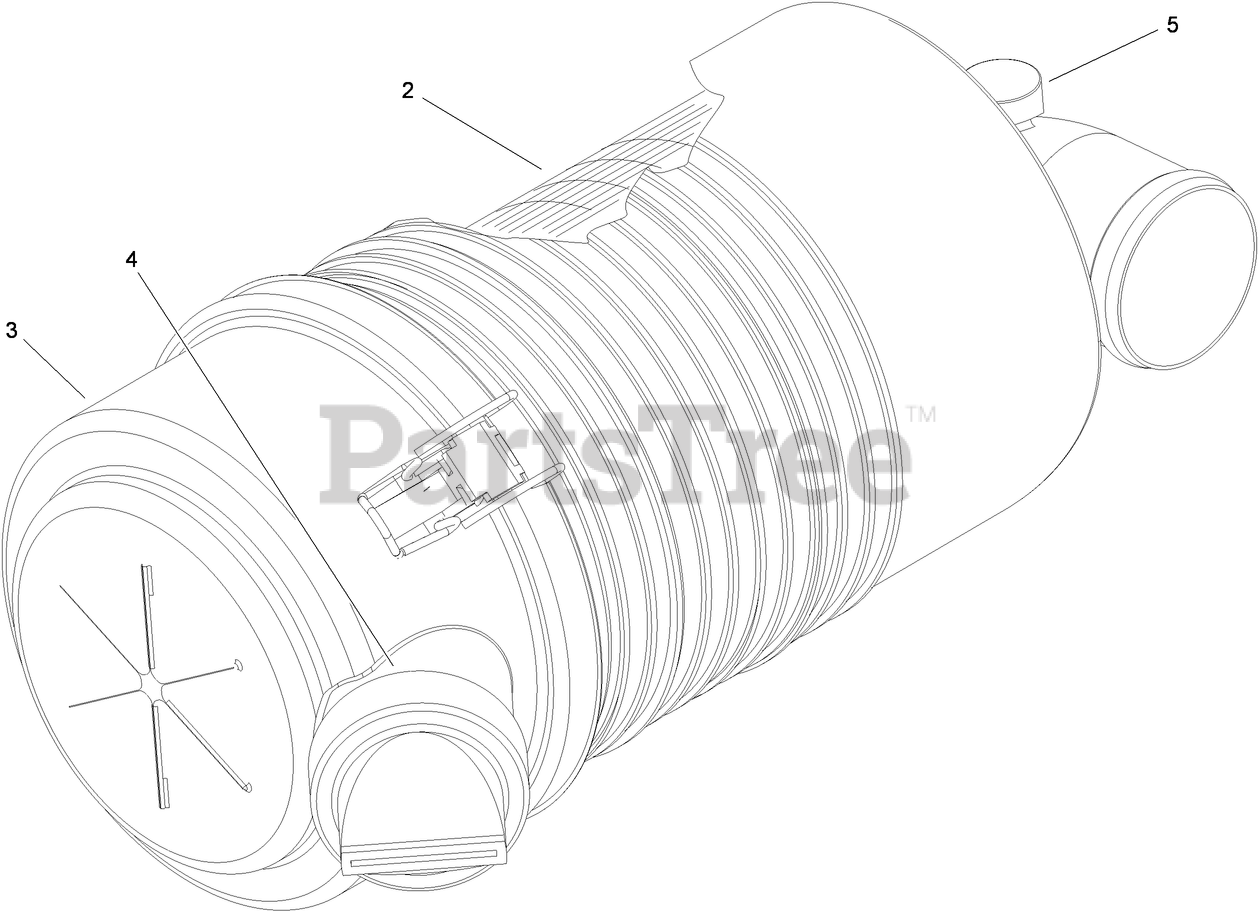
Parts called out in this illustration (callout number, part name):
2	FILTER-AIR
3	COVER ASM
4	VALVE-VACUATOR
5	PLUG-PIPE
